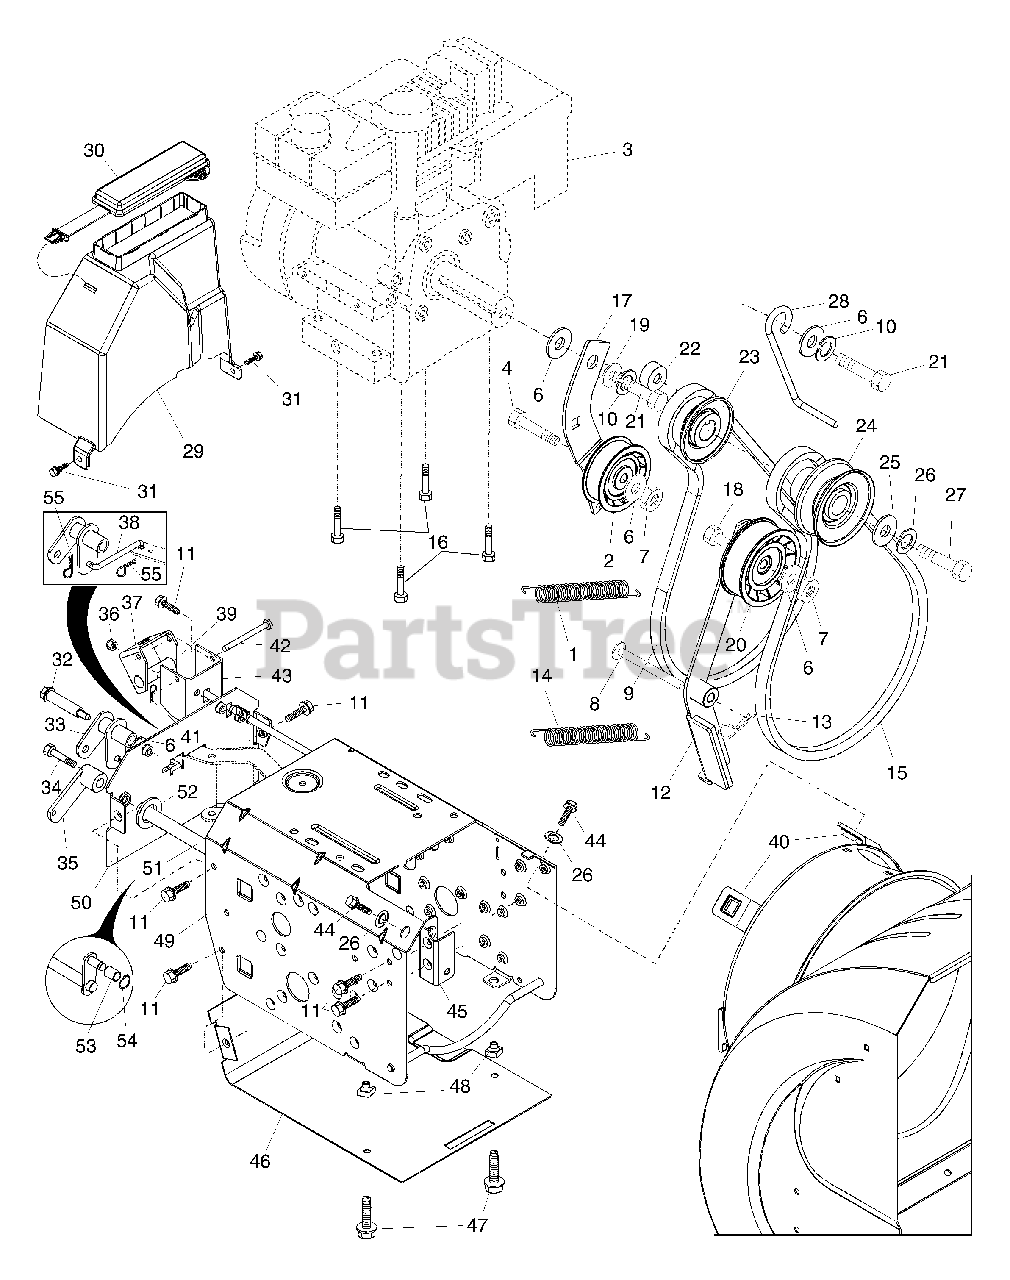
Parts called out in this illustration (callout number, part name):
1	Spring, Traction Idler
2	Pulley, Idler (2-1/4)
4	Screw, Hex Head 5/16-18 x 1-1/4
6	Washer, Flat
7	Nut, Jam, Lock 5/16-18
8	Pin, Idler Pivot
9	V-Belt, Traction Drive
10	Washer, Lock 5/16
11	Screw, Hex Head 5/16-18 x 3/4
12	Arm & Bracket Assembly, Impeller Idler
13	Retainer, Hairpin
14	Spring, Brake
15	V-Belt, Impeller Drive
16	Screw, Hex Head 3/8-16 x 1-1/4
17	Arm, Idler
18	Screw, Hex Head 5/16-18 x 1-1/2
19	Bushing, Idler Pivot
20	Pulley, Idler (2-3/4)
21	Screw, Hex Head 5/16-18 x 1
22	Spacer, Engine Pulley
23	Pulley, Engine, Traction Drive
24	Pulley, Engine, Impeller Drive
25	Washer, Flat 3/8
26	Washer, Lock 3/8
27	Screw, Hex Head 3/8-24 x 1-3/8
28	Guide, Belt
29	Cover, Belt
30	Cover, Toolbox
31	Screw, Hex Head 1/4-20 x 1/2
32	Bolt, Shoulder 5/16-18
33	Bellcrank Shifter
34	Screw, Hex Head 1/4-28 x 3/4
35	Arm, Auger Control
36	Nut, Lock 5/16-18
37	Bellcrank Assembly
38	Link, Speed Control
39	Trunnion, Pivot Bracket
40	Nut, Cage 3/8-16
41	Pin, Cotter 1/16 x 1/2
42	Pin, Pivot Bracket
43	Bracket, Bellcrank
44	Screw, Hex Head 3/8-16 x 1-1/2
45	Arm & Bracket Assembly, Impeller Idler
46	Pan, Frame Bottom
47	Screw, Hex Head 5/16-18 x 3/4
48	Nut, Speed 5/16-18
49	Frame Assembly
50	Plate, Frame End
51	Shaft, Auger Control
52	Washer, Hardened
54	Ring, Retaining
55	Clip, Retainer
